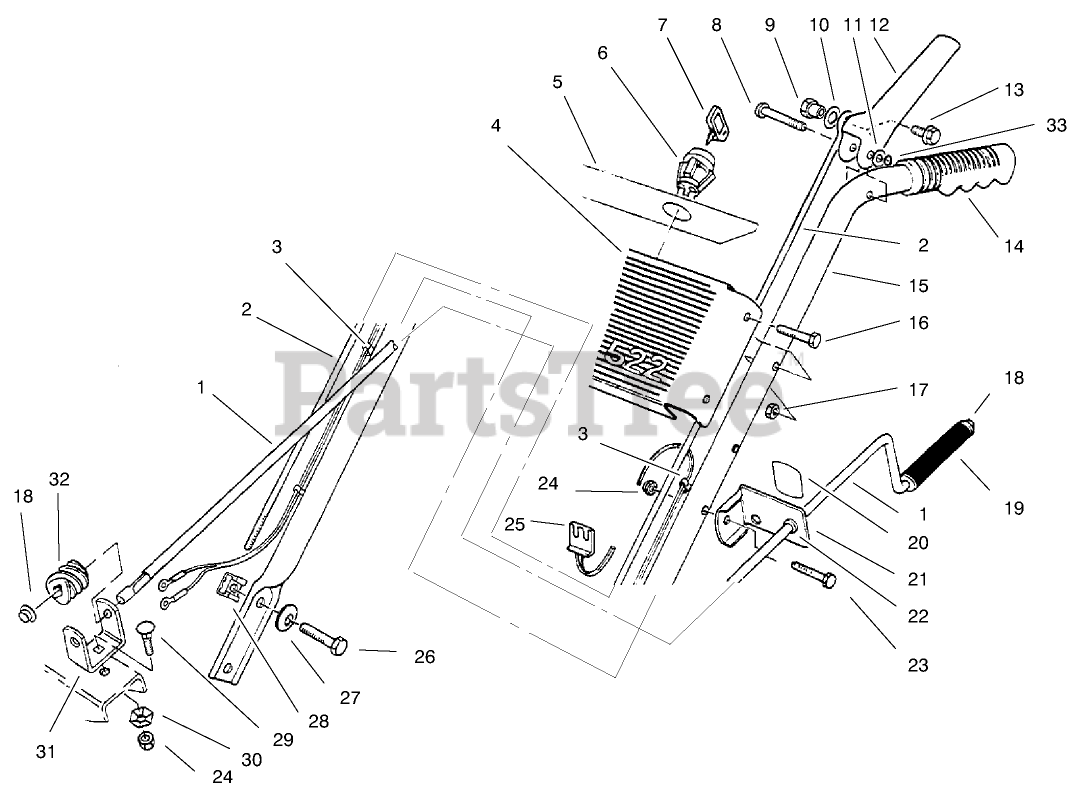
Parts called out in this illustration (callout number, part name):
1	ROD-CONTROL, CHUTE
2	LINK-UPPER
3	Mount-Wire
4	Panel-Escutcheon
5	DECAL - ESCUTCHEON BACK
6	SWITCH
7	KEY-IGNITION
8	PIN-LEVER, CONTROL
9	POST-MOUNTING, LINKAGE
10	WASHER-PLAIN
11	WASHER-FLAT
12	HANDLE-CONTROL
13	SCREW-HHF
14	GRIP-HANDLE
15	Handle-Left
16	SCREW-HH
17	NUT-LOCK, NI
18	RETAINER-PUSH ON
19	GRIP-CONTROL, CHUTE
20	DECAL-CHUTE DIRECTION
21	Bracket-Chute Control (Incl. Ref.# 20 & 22)
22	Bushing
23	SCREW-HH
24	NUT-LOCK, NI
25	Wire Harness Asm. (Incl. Ref.# 3)
26	SCREW-HH
27	WASHER-BELLEVILLE
29	SCREW-CARR
30	WASHER-LOCK
31	BRACKET-WORM
32	GEAR-WORM, CHUTE
33	RING-CLIP
